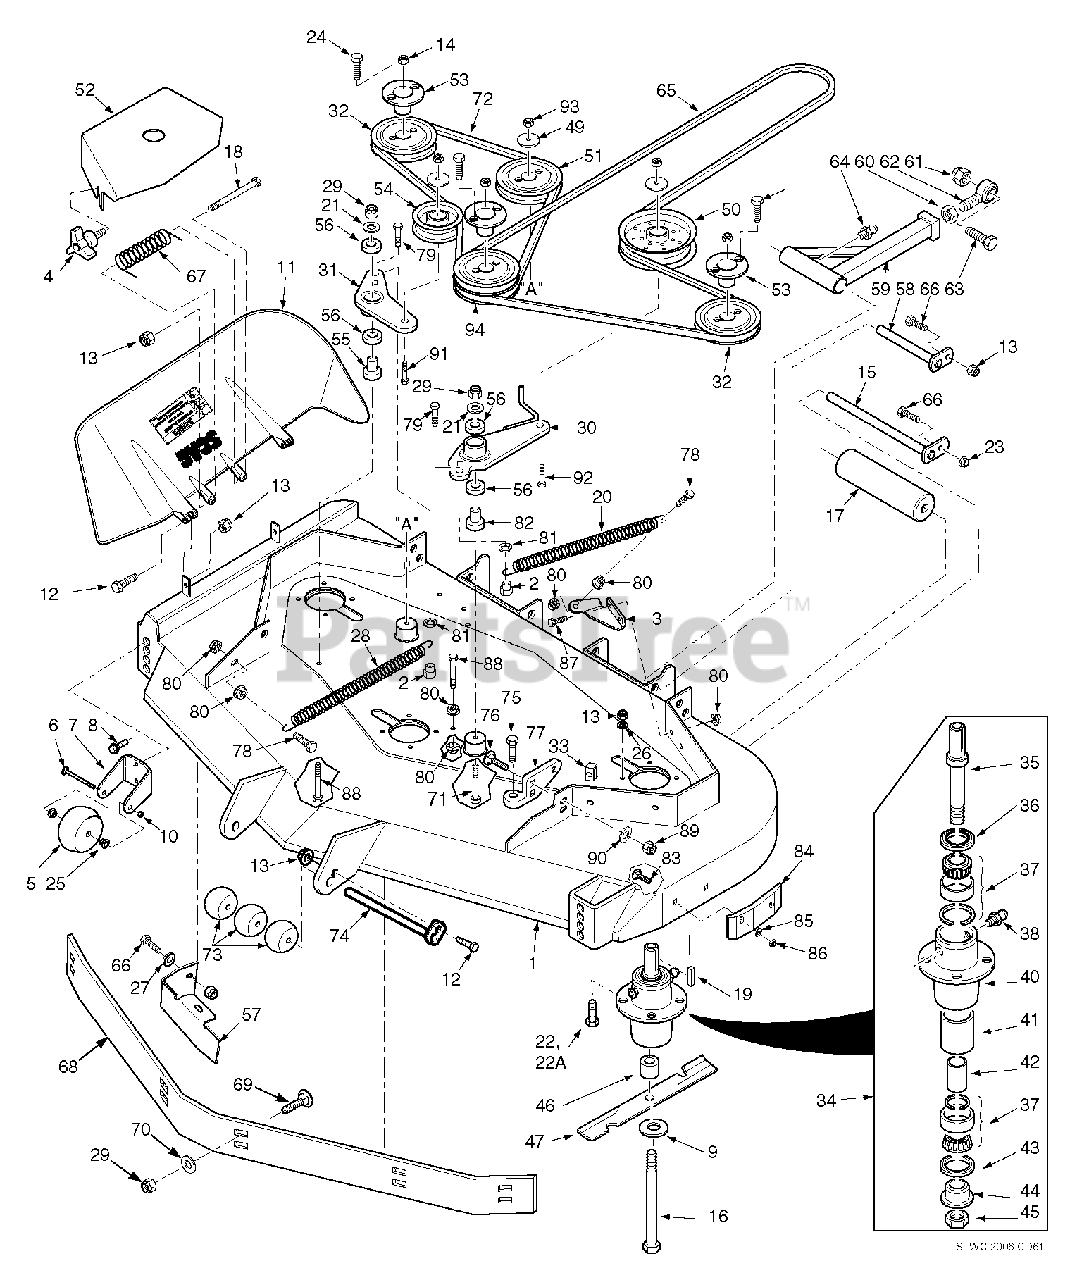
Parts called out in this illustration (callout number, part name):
1	Cutter Deck Velocity Plus
2	Boss, Spring Anchor
3	Bracket, LH Spring Anchor
4	Wing Nut, 3/8-16
5	Anti-Scalp Wheel
6	Bolt, Carriage 3/8-16 x 4"
7	Bracket, Anti-Scalp Wheel
8	Bolt, Serr. Flng. 3/8-16 x 1"
9	Flatwasher, 5/8" Hardened
10	Locknut, 3/8-16 Center Lock
11	Discharge Chute
12	Bolt, Hex Hd. 5/16-18 x 1-1/2", Rear
13	Nut, Elastic Stop 5/16-18
14	Nut, 5/8-11 UNC
15	Shaft, Roller
16	Bolt, Hex Hd. 5/8-11 x 9-1/2"
17	Roller, Rear
18	Bolt, Hex Hd. 5/16-18 x 4-3/4"
19	Key, 1/4 x 1/4 x 2"
20	Spring, LH Deck Drive
21	Flatwasher, 3/8" (.938 x .391 x .105")
22	Bolt, Hex Hd. 5/16-18 x 1-3/4" Grd. 8
23	Nut, Serr. Flng. 5/16-18
24	Bolt, Hex Hd. 1/4-20 x 1" Grd. 8
25	Bushing, .376 ID Oilite(R)
26	Lockwasher 5/16"
27	Flatwasher 5/16"
28	Spring, RH Deck Drive
29	Nut, Elastic Stop 3/8-16
30	Idler Arm Assembly, LH Drive
31	Idler Arm Assembly, RH Drive
32	Pulley, Tapered Bore 6.33" Dia.
33	U-Nut, 3/8-16
34	Spindle Assembly
35	Shaft, Spindle
36	Seal Upper
37	Bearing Assembly
38	Grease Fitting
39	Valve, Grease Relief
40	Housing, Spindle
41	Spacer, Outside
42	Spacer, Inside
43	Seal, Lower
44	Bushing, Bottom
45	Nut, Special 1-1/16 - 18
46	Spacer, Spindle
47	Cutter Blade 21"
48	Pulley, Double Groove 6.33" Dia.
49	Dust Shield
50	Idler Pulley, 5" Dia.
51	Idler Pulley, 5" Dia.
52	Belt Cover
53	Hub, Tapered 1-1/8" Bore
54	Idler Pulley, 3-1/2" Dia.
55	Pivot, Idler
56	Bearing
57	Turbo Baffle, Bolt On
58	Push Arm Shaft
59	Push Arm
60	Nut, 5/8-18 UNF
61	Nut, Elastic Stop 5/8-11
62	Rod End, 5/8 Male RH Thread
63	Bolt, Hex Hd. 5/8-11 x 4-1/2"
64	Grease Fitting, 90 Degree
65	Belt, Deck Drive 61V
66	Bolt, Hex Hd. 5/16-18 x 1"
67	Spring, Discharge Chute
68	Baffle Weldment, 61V
69	Bolt, Carriage 3/8-16 x 1"
70	Flatwasher, 3/8 (.391 x .938 x .105")
71	Bolt, Hex Hd. 3/8-16 X 3-1/2"
72	Belt, Deck Drive RH
73	Wheel, Anti Scalp
74	Roller Shaft
75	Bolt, Special
76	Bolt, Carriage 7/16-14 x 1-1/4"
77	Lever Assy., Deck Level
78	Bolt, Hex Hd. 3/8-16 x 1-1/2" Grd. 8
79	Bolt, Hex Hd. 3/8-16 x 1"
80	Nut, Serr. Flng. 3/8-16
81	Lockwasher, 5/16"
82	Pivot, Idler Short
83	Bolt, Carr. 5/16-18 x 3/4"
84	Wear Pad
85	Flatwasher, 5/16 (.344 x .688 x .065")
86	Nut, Center Lock 5/16"
87	Bolt, Hex Hd. 3/8-16 x 1"
88	Bolt, Hex Hd. 3/8-16 x 2-1/2"
89	Nut, Elastic Stop 7/16-14
90	Flatwasher, 7/16 (.500 x 1.250 x .083")
91	Bolt, Hex Hd. 3/8-16 x 2-1/4"
92	Bolt, Hex Hd. 3/8-16 x 3"
93	Nut, Elastic Stop 3/8-16
94	Pulley, Double Groove 6.33" Dia.
